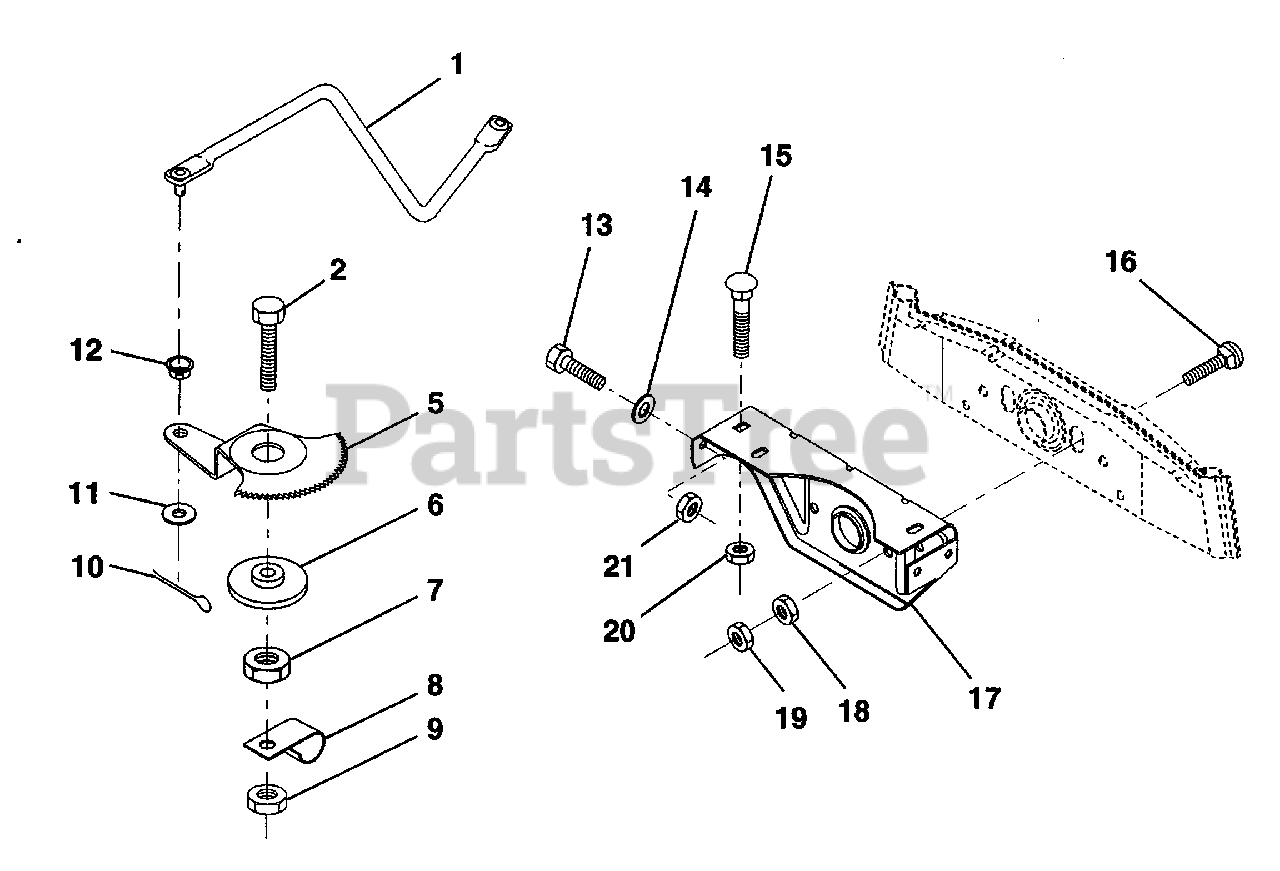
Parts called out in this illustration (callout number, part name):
1	Link, Drag (AYP part number)
2	Bolt, Hex, Fin. 1/2-13 x 1-3/4 (AYP part number)
5	Gear, Sector (AYP part number)
6	Bushing (AYP part number)
7	Nut, Heavy, Hex Head, Top Lock 1/2-13 UNC (AYP part number)
8	Clip, Wire (AYP part number)
9	Nut, Crownlock 1/2-13 (AYP part number)
10	Pin, Cotter 1/8 x 3/4 (AYP part number)
11	Washer 13/32 x 13/16 x 16 Gauge (AYP part number)
12	Bushing (AYP part number)
13	Bolt, Hex 5/16-18 UNC x 3/4 (AYP part number)
14	Washer 11/32 x 7/8 x 16 Gauge (AYP part number)
15	Bolt, Carriage 3/8-16 UNC x 3/4 (AYP part number)
16	Bolt, Carriage 3/8-16 x 2-3/4 (AYP part number)
17	Support, Front Axle (AYP part number)
18	Nut, Hex, Fin. 3/8-16 UNC (AYP part number)
19	Nut, Centerlock 3/8-16 UNC (AYP part number)
20	Nut, Crownlock 3/8-16 UNC
21	Nut, Crownlock 5/16-18
